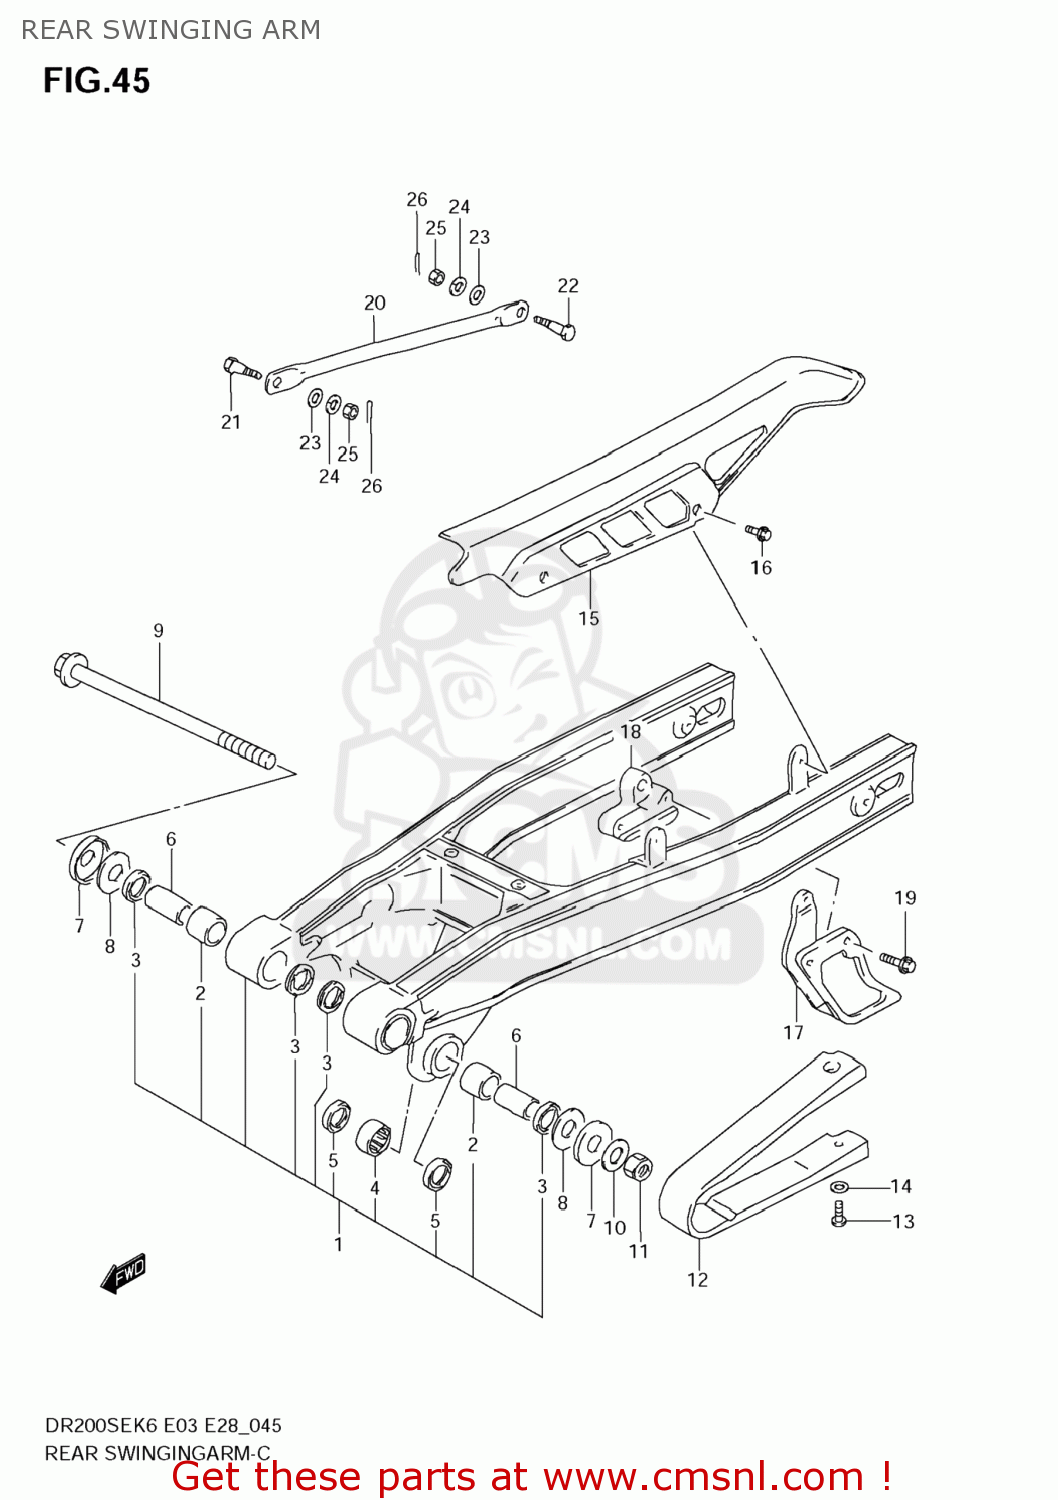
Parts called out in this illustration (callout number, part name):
1	SWINGINGARM ASSY,RR
2	BUSHING,RR SWGARM PIVOT
3	SEAL,OIL(20X27X5)
4	BEARING(20X27X25)
5	SEAL,CUSHION LEVER OUT DUST
6	SPACER,RR SWGARM PVT
7	COVER,RR SWGARM DUST SEAL
8	WASHER
9	SHAFT,RR SWINGINGARM PIVOT
10	WASHER(14.5X24X2.3)
11	NUT
12	BUFFER,CHAIN TOUCH DEFENSE
13	SCREW
14	WASHER
15	CASE,CHAIN
16	BOLT(6X10)
17	GUIDE,CHAIN
18	RUBBER,CHAIN GUIDE
19	BOLT
20	TORQUELINK,RR
21	BOLT(8X28)
22	BOLT(8X26.5)
23	WASHER
24	WASHER,LOCK
25	NUT
26	PIN
